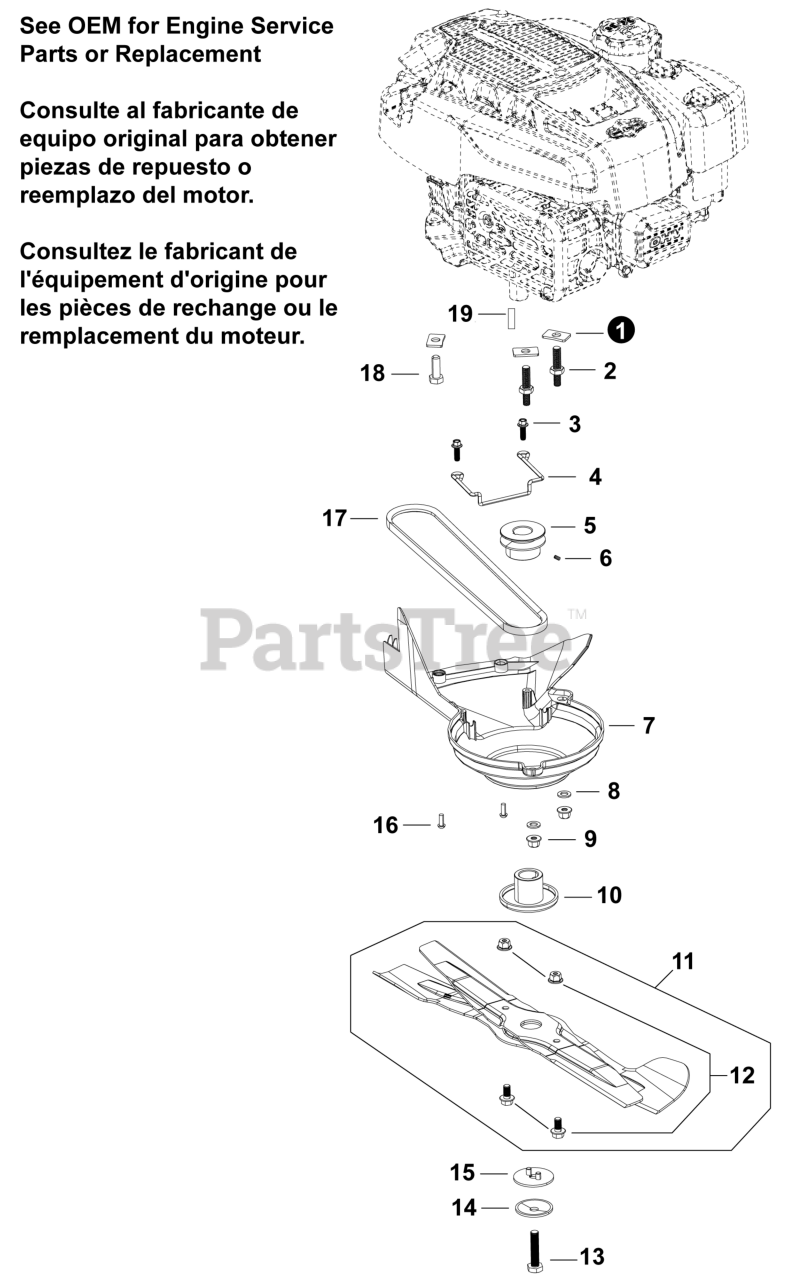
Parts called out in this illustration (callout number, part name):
2	BOLT, ENGINE MOUNTING
4	GUIDE, BELT
5	PULLEY, DRIVE
6	SCREW, SET
7	GUARD, BELT
10	ADAPTOR, BLADE
11	BLADE SET
12	BLADE BOLT & NUT SET - NESTING
13	BOLT, BLADE MOUNTING
15	PLATE, PRESSURE
17	BELT, SELF-PROPEL
18	BOLT, ENGINE MOUNTING
19	KEY, FLAT
